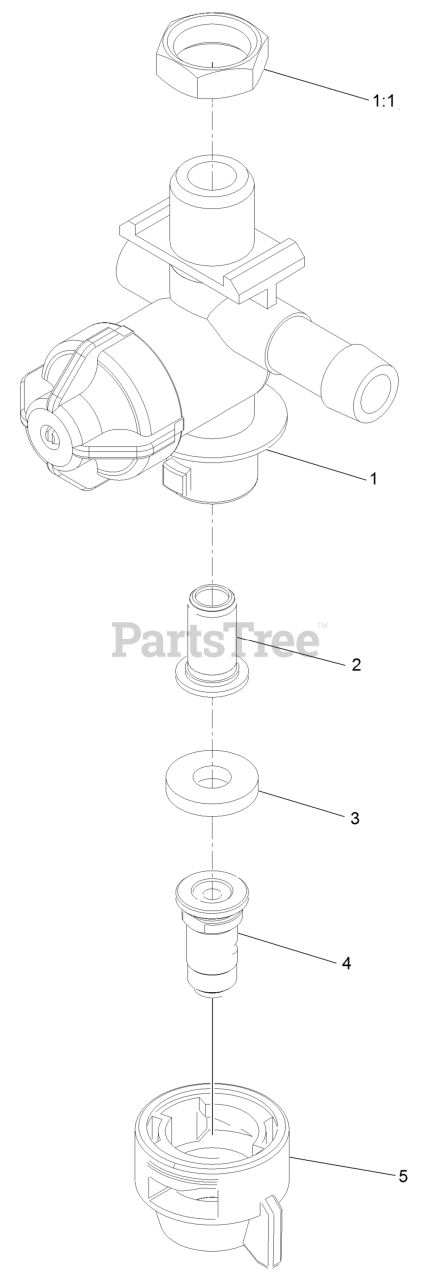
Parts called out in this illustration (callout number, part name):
1	LH NOZZLE BODY ASM
1:1	NUT-NYLON
2	STRAINER-TIP
4	NOZZLE-SPRAY, WHITE
5	CAP-NOZZLE
